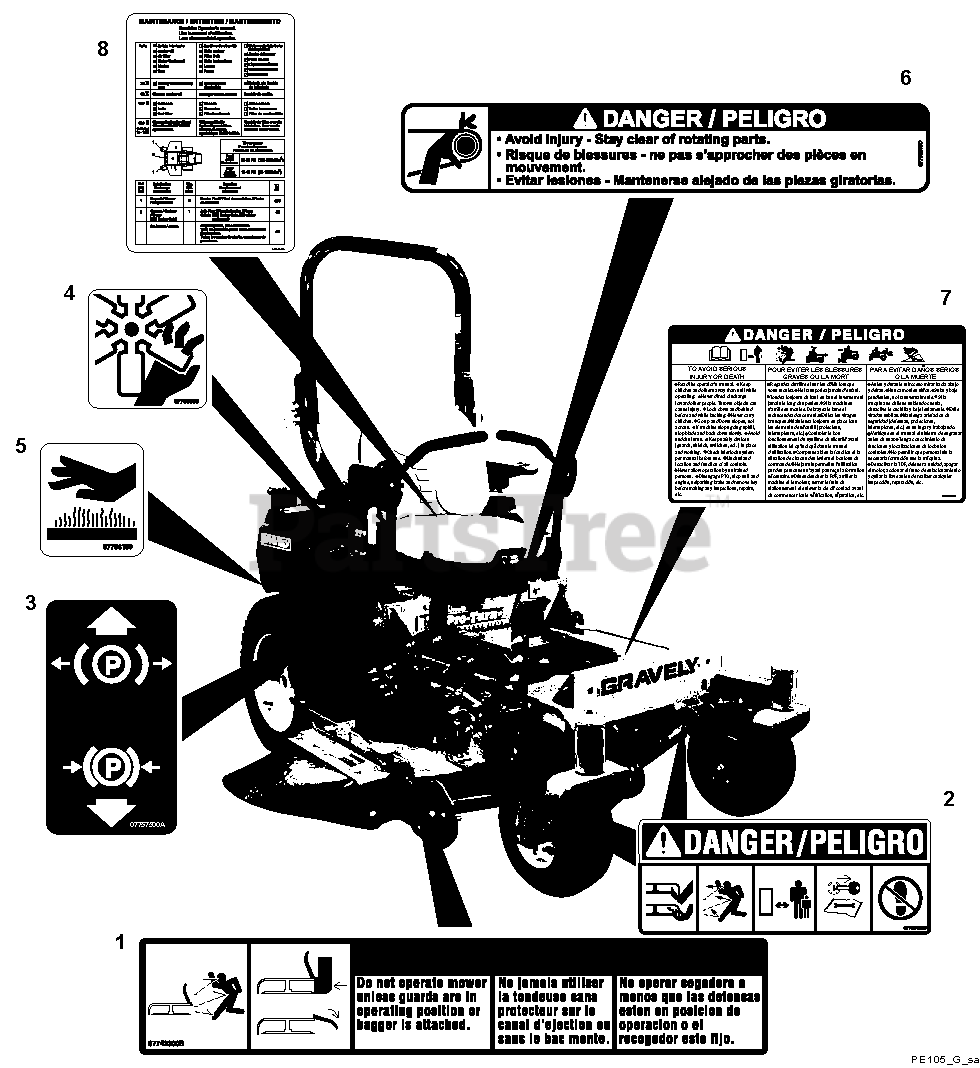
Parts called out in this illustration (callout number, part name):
1	Decal, Warning
2	Decal, Mower Pan Danger
3	Decal, Parking Brake Lever
4	Decal, Danger Fan
5	Decal, Hot Surface
6	Decal, Danger Rotating Parts
7	Decal, Danger-Bilingual
8	Decal, Maintenance Instructions
